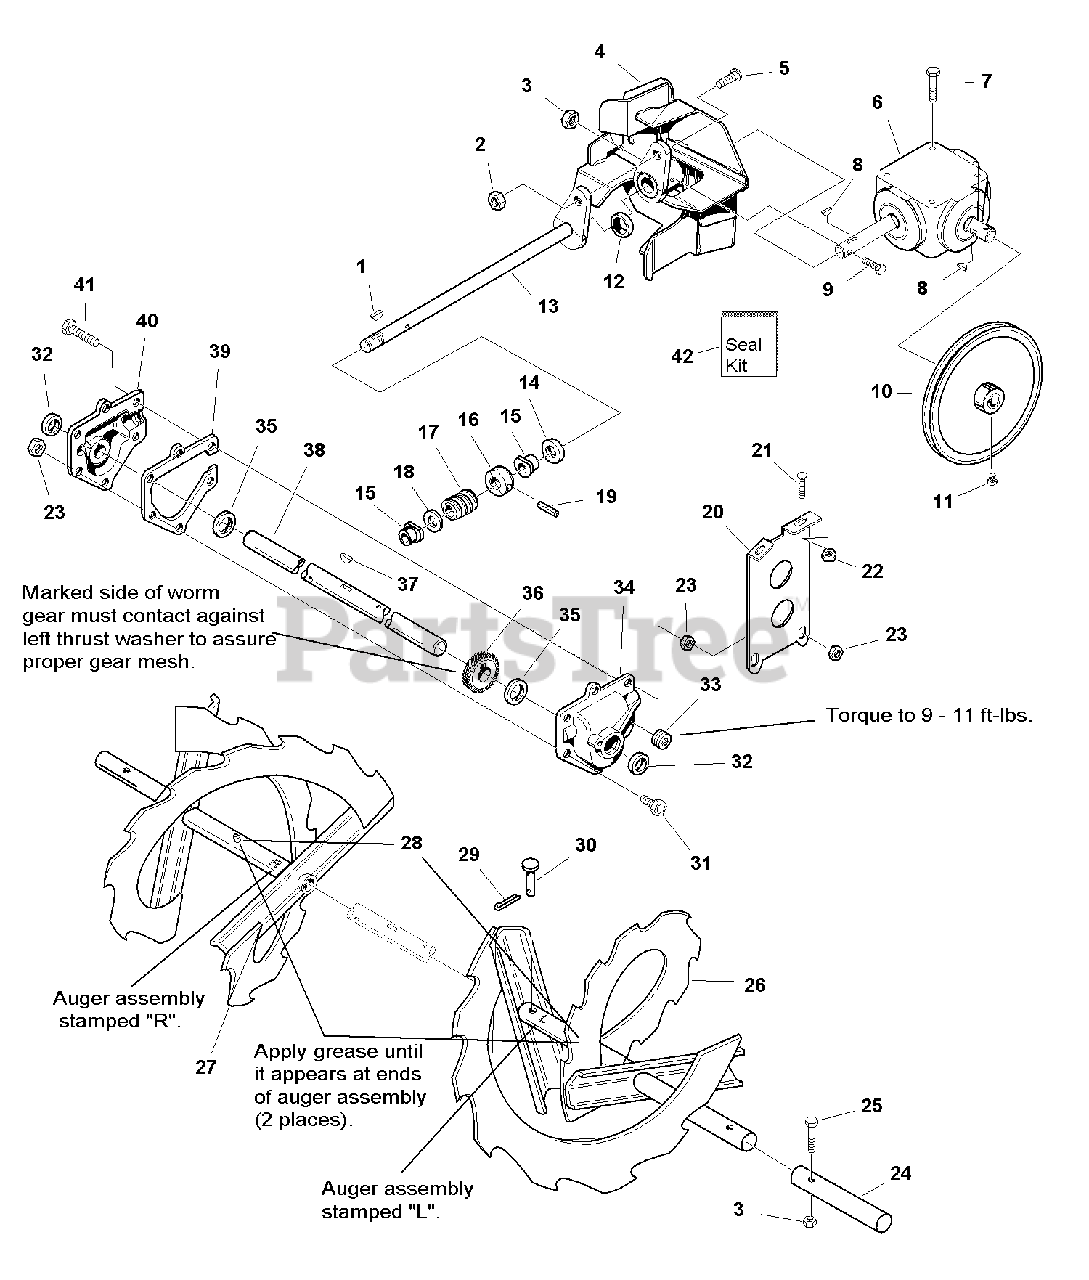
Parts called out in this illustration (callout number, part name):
1	KEY, Woodruff, 3/16 x 5/8
2	NUT, Hex Lock ESNA, 5/16-18
3	NUT, Hex Lock ESNA, 1/4-20
4	IMPELLER ASSEMBLY, 42"
5	CARRIAGE BOLT, 5/16-18 x 1, Black
6	GEARBOX ASSEMBLY, 42"
7	CAPSCREW, Hex Whiz Lock, 3/8-16 x 3/4
8	KEY, Hi Pro, 1/4 x 7/8
9	CAPSCREW, Hex Head, 1/4-20 x 1-7/8, Black
11	SETSCREW, Square Head, 5/16-18 x 1/2
13	SHAFT, Worm
15	BUSHING, Flange
16	COLLAR, Thrust
17	GEAR, Rolled Worm
18	WASHER, Thrust
19	PIN, Drivelok, 3/16 x 1-1/2
20	SUPPORT, Gear Box
21	CARRIAGE BOLT, 5/16-18 x 3/4
22	NUT, Hex Flange Whiz Lock, 5/16-18
23	LOCKNUT, Hex, 1/4-20
25	CAPSCREW, Hex Head, 1/4-20 x 1-3/4
26	AUGER ASSEMBLY, LH, 42"
27	AUGER ASSEMBLY, RH, 42"
28	FITTING, Lube, 1/4
29	PIN, Cotter, 3/32 x 3/4
30	PIN, Shear
31	CAPSCREW, Hex Head, 1/4-20 x 7/8
33	PLUG, Pipe, Tapered, 1/8
34	CASE, Gear, LH
35	WASHER, Thrust
36	GEAR, Worm
37	KEY, Woodruff, 1/4 x 3/4
38	SHAFT, Auger
40	CASE, Gear, RH
41	CAPSCREW, Hex Head, 1/4-20 x 2-1/2
42	SEAL KIT, for Gear Box, Reference No. 6
